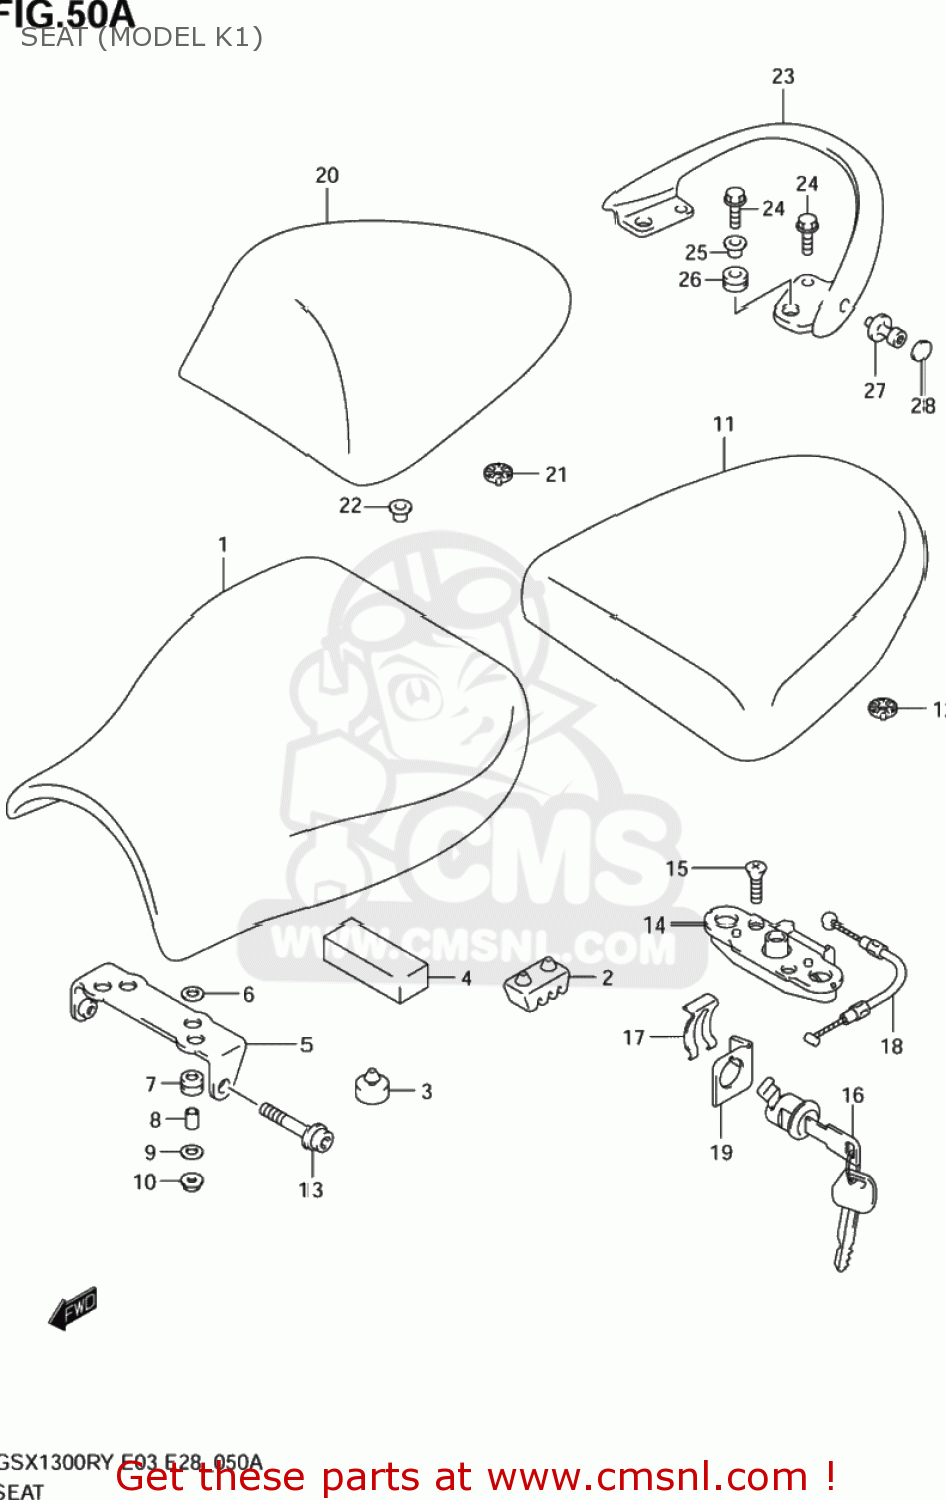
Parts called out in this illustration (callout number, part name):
1	SEAT ASSY(BLACK)
2	CUSHION,SUPPORT(50X25X32)
3	CUSHION
4	CUSHION,CTR
5	BRACKET,SEAT
6	WASHER(6.5X20X1.6)
7	CUSHION,SEAT
8	SPACER(6.5X10X10)
9	WASHER,SEAT BRACKET
10	NUT
11	SEAT ASSEMBLY,PILLION
12	CUSHION
13	BOLT,SEAT FR
14	BRACKET,SEAT SUPPORT,RIGHT
15	SCREW
16	LOCK SET,SEAT
17	PLATE,SEAT LOCK ASSY
18	CABLE,SEAT LOCK
19	GUIDE,SEAT LOCK CABLE
20	BOX COMP,SEAT
21	CUSHION
22	WASHER COMP,FRAME COVER
23	HANDLE,PILLION RIDER(GRAY)
24	BOLT(8X35)
25	WASHER,PILLION
26	CUSHION,PILLION RIDER HANDLE
27	HOOK,PILLION RIDER HANDLE
28	CAP(OD:10)
